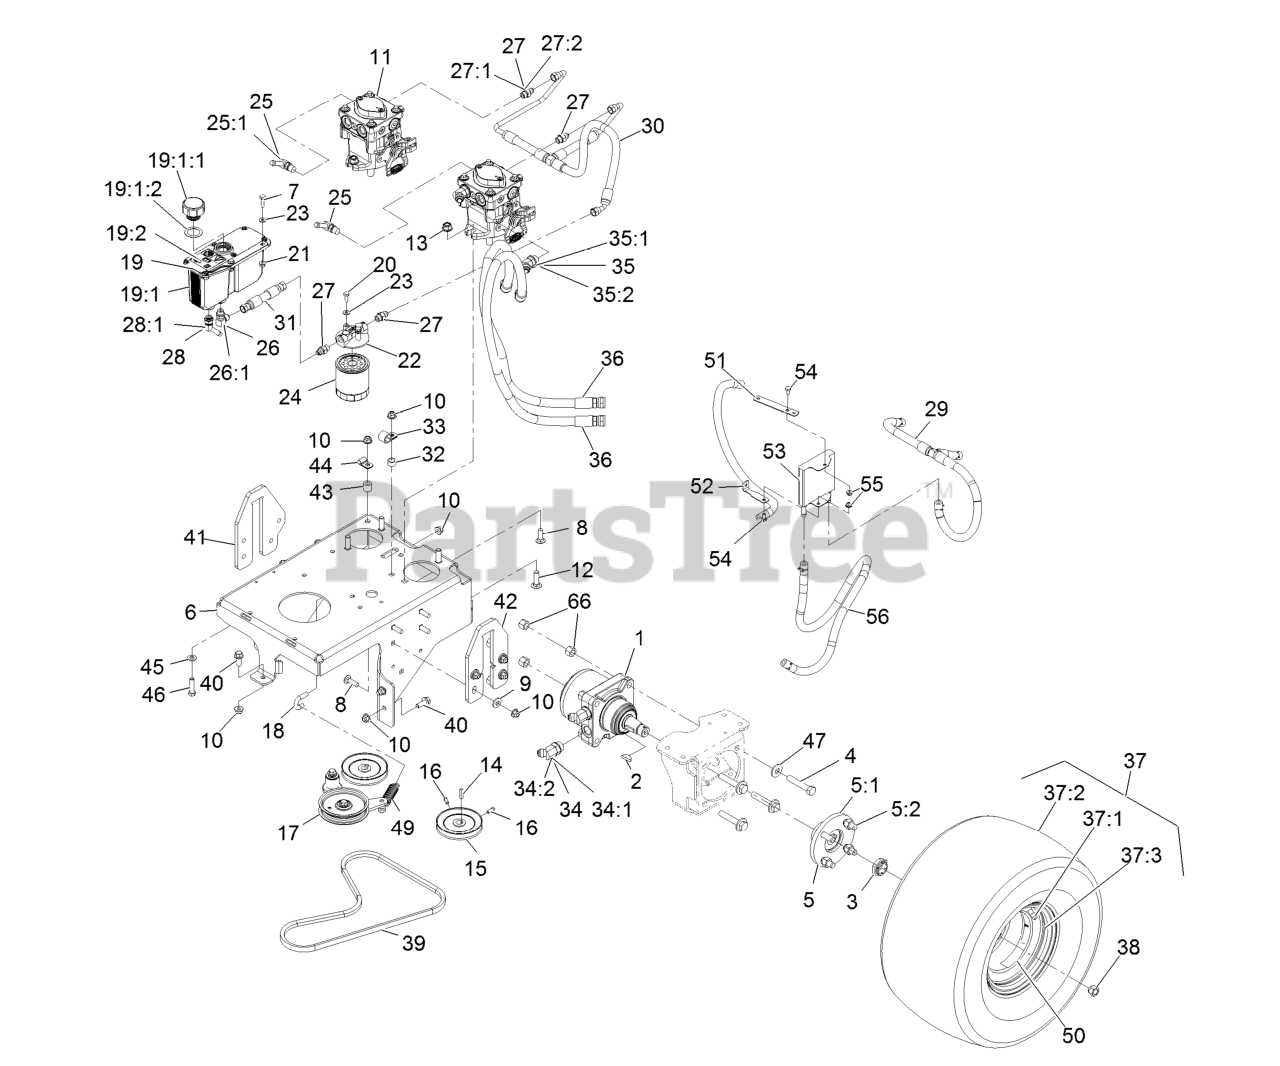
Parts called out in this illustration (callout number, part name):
1	MOTOR-WHEEL
2	KEY-WOODRUFF
3	LOCKNUT
4	SCREW-HH
5	WHEEL HUB / STUD ASM
5:1	HUB-WHEEL
5:2	STUD-TYPE, DRIVE
6	BASE, ENGINE
7	SCREW-HH
8	BOLT-CARR
9	WASHER-BELLEVILLE
10	NUT-HF, NI
11	PUMP - HYDRAULIC
12	SCREW-HH
13	NUT-HF, NI
15	PULLEY-PUMP
16	SCREW-SET
17	PUMP IDLER ASM
18	ANCHOR, SPRING
19	RESERVOIR ASM
19:1	Reservoir-Hyd
19:1:1	Cap-Reservoir, HYD
19:1:2	GASKET-CAP
19:2	DECAL-WARNING
20	SCREW-HH
21	NUT-HHF
22	HEAD-FILTER
23	WASHER-FLAT
24	FILTER-25 MICRON, BI-DIRE
25	FITTING-ELBOW, 90
25:1	O-RING
26	FITTING-ELBOW, 90 DEG
27	FITTING-STRAIGHT
28	FITTING-BARBED, 45 DEG
28:1	O-RING
29	HOSE ASM-CASE DRAIN
30	HOSE ASSEMBLY - CHARGE
31	HYD HOSE ASM
32	SPACER-WHEEL
33	CLIP-LOOM
34	FITTING-HYD, 45 DEG
35	FITTING-HYD, 45 DEG
36	HYD HOSE ASM
37	WHEEL/TIRE ASM
37:1	RIM-8 INCH
37:3	Stem-Valve
38	NUT-LUG
39	BELT-V, LOWER PTO
40	SCREW-HHF 3/8-16 X 1
41	PLATE-LIFT, RH
42	PLATE, LIFT LH
44	CLIP-TUBE
45	WASHER-FLAT
46	SCREW-HH
47	WASHER-SPRING
49	SPRING-EXTENSION
50	DECAL-TORQUE, WHEEL HUB LUG
51	BRKT-COOLER MOUNT, TOP
52	BRKT-COOLER MOUNT, BOTTOM
53	COOLER-OIL
54	SCREW-HH
56	HOSE ASM
66	NUT-LOCK, NI
